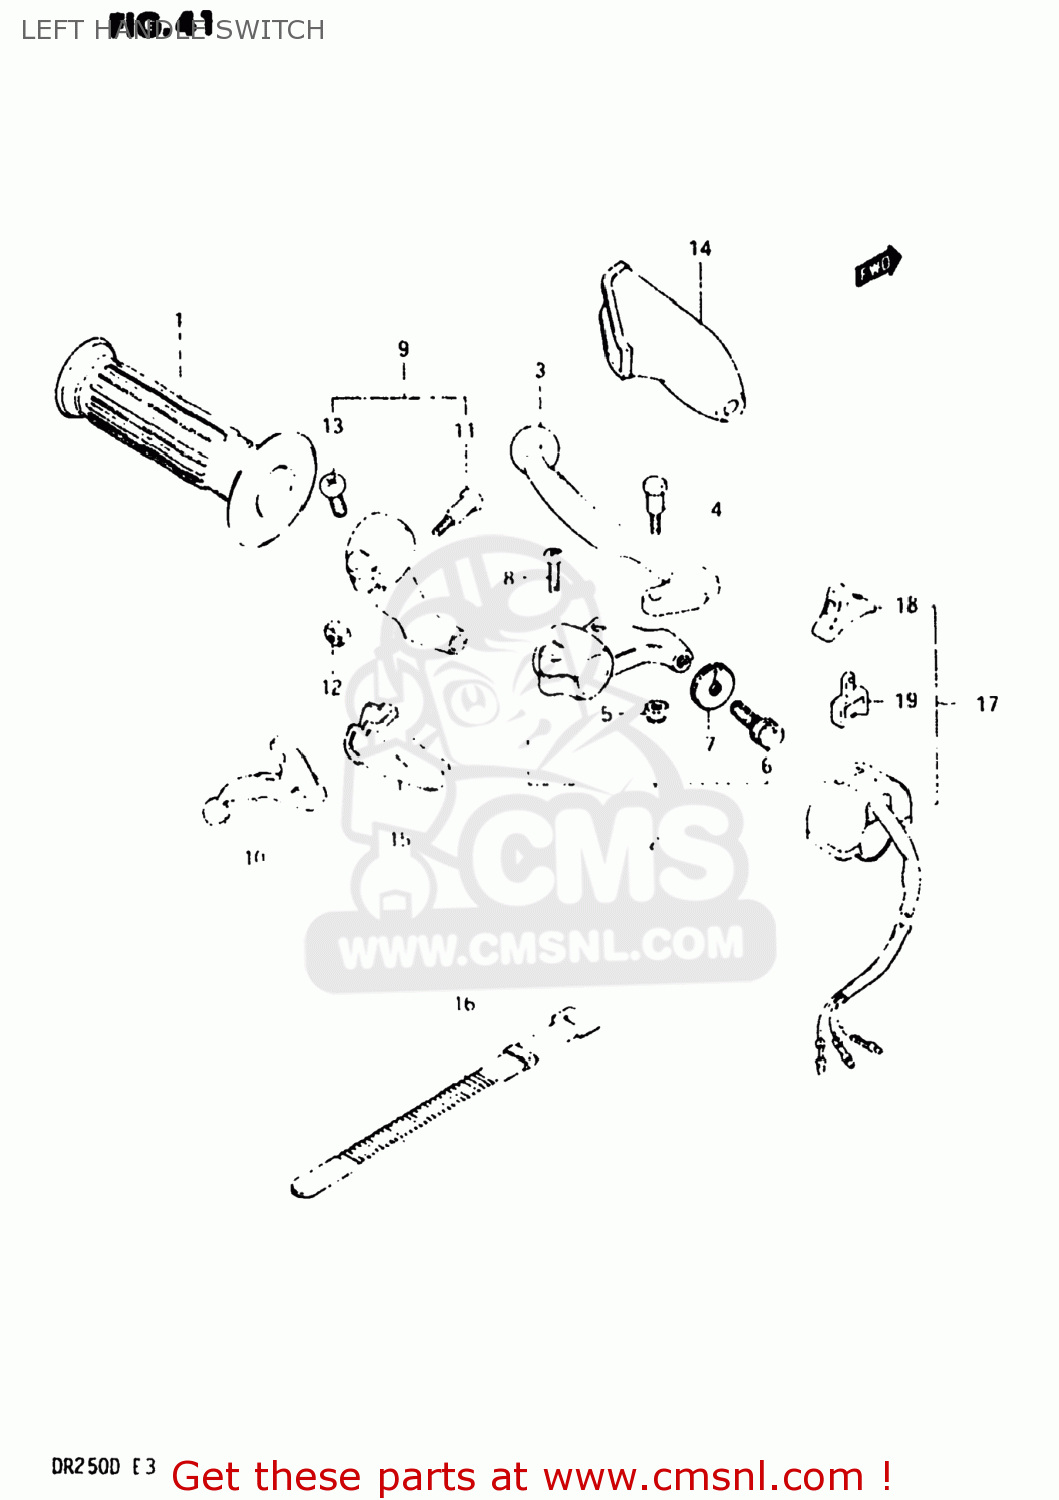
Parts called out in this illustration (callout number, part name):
1	GRIP,L
2	LEVER ASSY,CLUTCH
3	LEVER,CLUTCH
4	BOLT,LEVER
5	NUT 6MM
6	ADJUSTER,CABLE
7	NUT,CABLE ADJUSTER
8	SCREW
9	LEVER ASSEMBLY,DECOMPRESSION
10	LEVER,DECOMP
11	BOLT,LEVER
12	NUT
13	SCREW
14	COVER,CLUTCH LEVER
15	COVER,DECOMP LEVER DUST
16	CLAMP(L:120)
17	SWITCH ASSY,LIGHTING
18	KNOB,LIGHTING & DIMMER
19	BLOCK,LIGHTING/DIMMER
